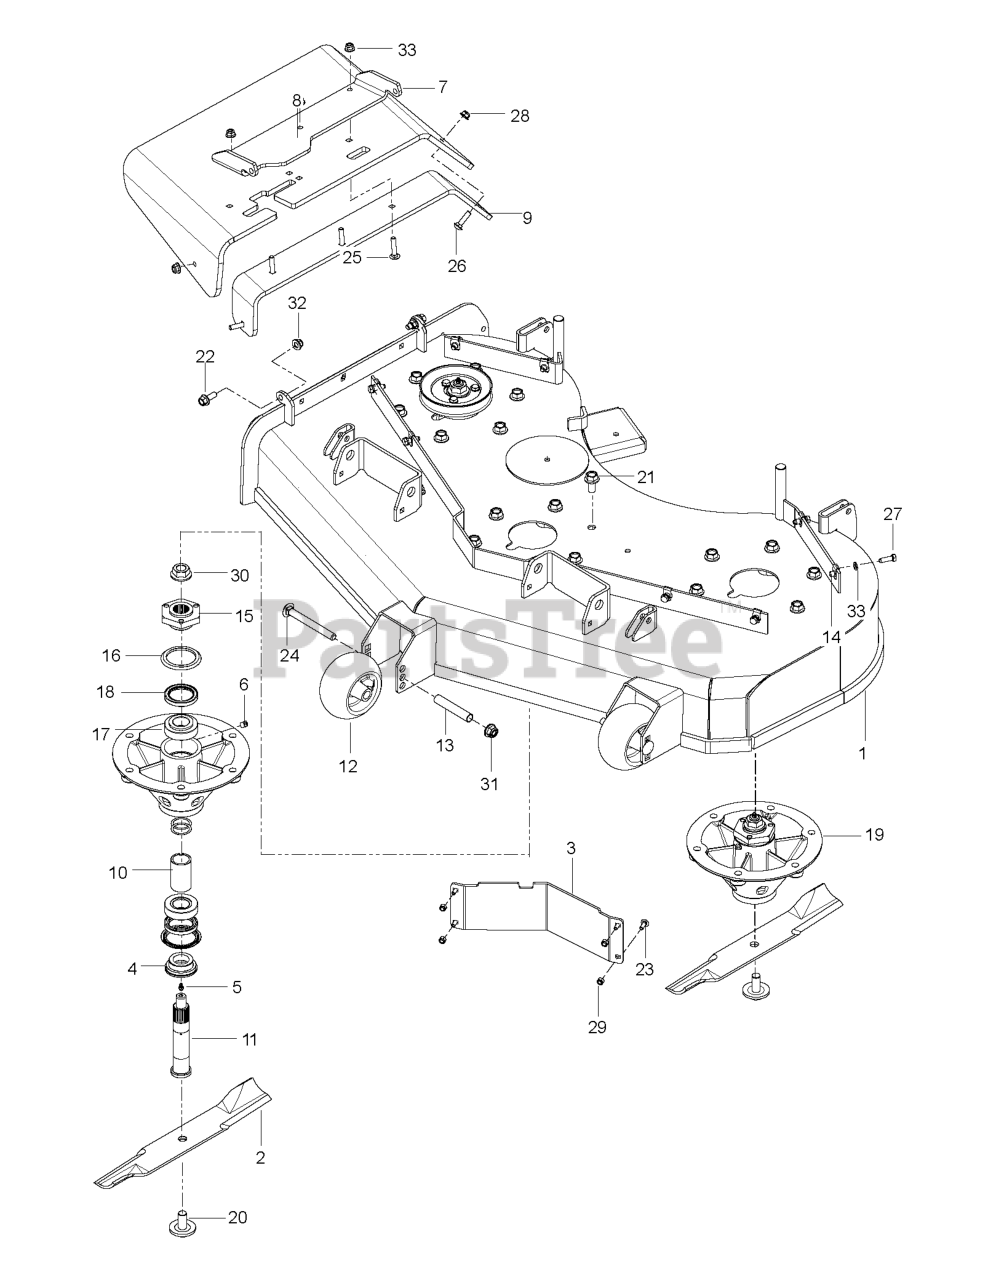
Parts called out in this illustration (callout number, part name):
1	DECK.SVC.W/DCLS.CZT.48X.MS672
2	BLADE 17" HIGHT LIFT
3	BAFFLE, DIVERTER 54"/60" LH
5	ZERK
6	PLUG-VENTED
7	BRKT - CHUTE MTG BLACK
8	CHUTE, DISCHARGE 48-52
9	BRKT, CHUTE SUPPORT BLACK
12	ROLLER, GAUGE .635 BORN
13	TUBE, ROLLER AXLE
14	U-CLIP 5/16-18 NUT RETAINER
16	SEAL V-RING 55MM
17	BEARING
18	SEAL SHAFT
19	SPINDLE.ASM.10".ALUM.1/8-27
20	BLADE BOLT/WASHER
21	HHFS 1/2-13 X 1 GR5 ZD
22	HHFS 3/8-16 X 1 GRD 5 ZD
23	1/4-20X3/4 CARR BLT
24	RHSNB 1/2-13 X 4.75 GR5 ZD
25	RHSNB 5/16-18 X 1-1/2 GR 5 ZD
26	BOLT, CARRIAGE 5/16X1-1/4
27	HCS 5/16C X 1
28	5/16-18 NYLOC FLANGE NUT
29	RP_NUT 1/4-20 NYLOC
30	NUT FLANGE 3/4-16
31	NUT, 1/2-13 HEX FLG NYLOC ZD
32	NUT 3/8-16 HEX FLG NYLOC ZD
33	WASHER 5/16 LOCK
